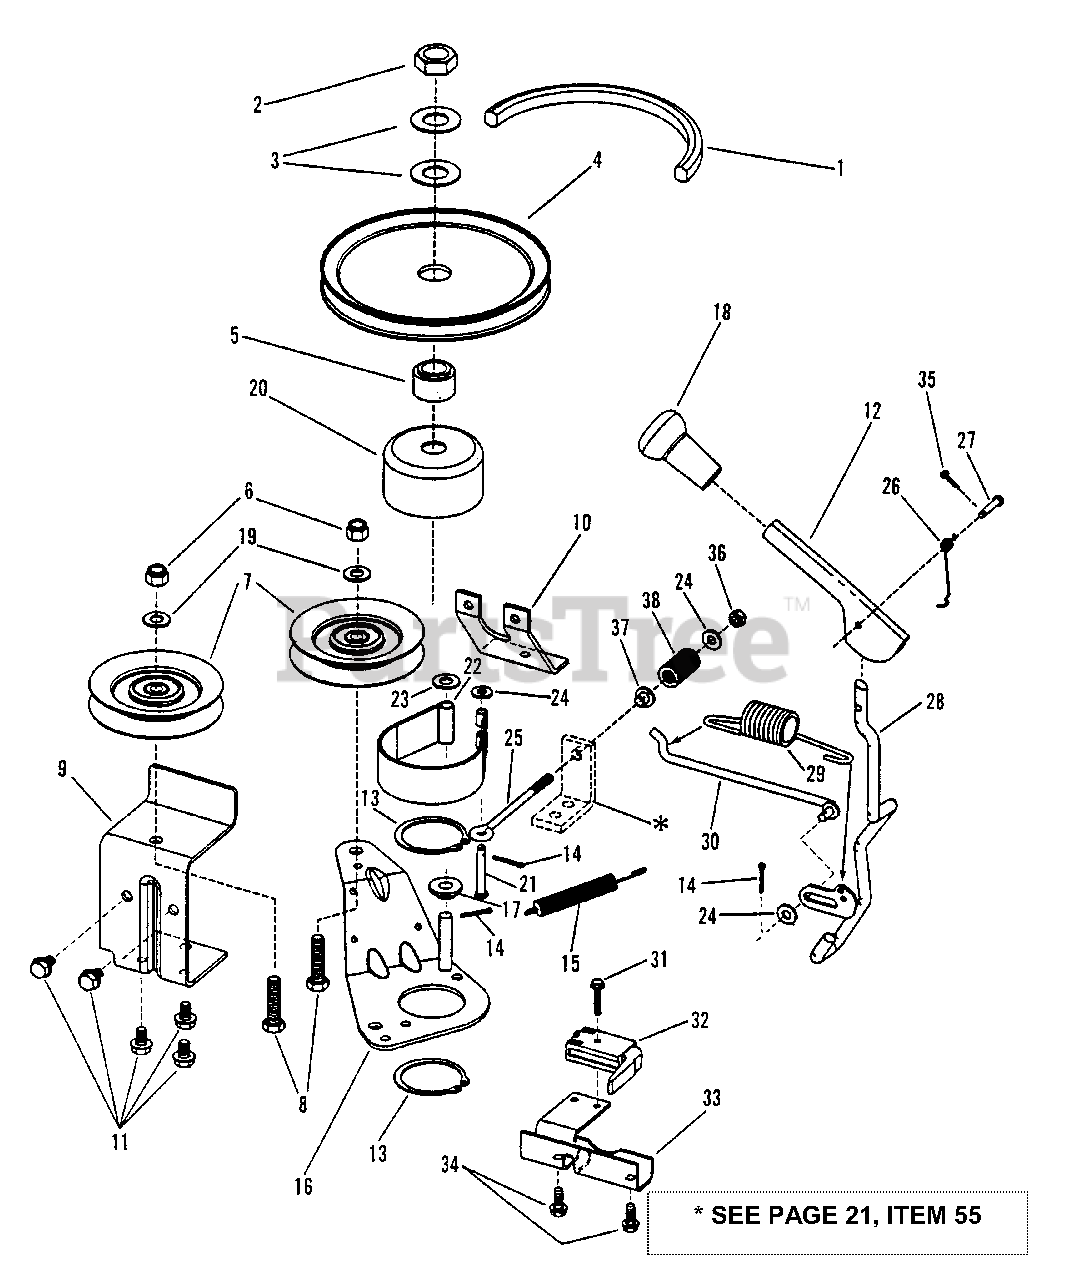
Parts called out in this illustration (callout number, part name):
1	BELT, Drive (74.75" AA Section)
2	NUT, 3/4-16 Hex Jam
3	WASHER, 49/64" I.D. x 1-1/2" O.D. Flat
4	PULLEY, Spindle
5	HUB, Pulley
6	NUT, 3/8-16 Nyloc
7	PULLEY, 4" Idler
8	SCREW, 3/8-16 x 1-1/2" Hex Head Cap, Grade 5
9	BRACKET, Fixed Idler
10	BRACE, Fixed Idler
11	SCREW, 5/16-18 x 1/2" Hex Washer Self-Tap
12	HANDLE, Blade Engage (Flip)
13	RING, 2" External Retaining
14	PIN, 3/32 x 3/4" Cotter
15	SPRING, Extension, 4" x 1/2" Diameter
16	WELDMENT, Idler Arm
17	SPACER
18	GRIP, Handle
19	WASHER, 3/8" Flat
20	DRUM, Brake
21	PIN, 1/4" x 1-5/8" Clevis
22	BAND, Brake
23	WASHER, 3/8" Flat
24	WASHER, 1/4" Flat
25	EYE-BOLT, 1/4-20 x 4"
26	SPRING, Flip Handle
27	PIN, 3/16 x 1" Clevis
28	HANDLE, Blade Lever (ON-OFF)
29	SPRING, Blade Handle
30	ROD, Idler
31	SCREW, #10-32 x 1" Hex Washer Self-Tap
32	SWITCH, Deck Interlock
33	MOUNT, Handle
34	SCREW, 1/4-20 x 5/8" Hex Washer Self-Tap
35	PIN, 3/32 x 1/2" Cotter
36	NUT, 1/4-20 Hex Top Lock
37	BUSHING
38	SPRING
